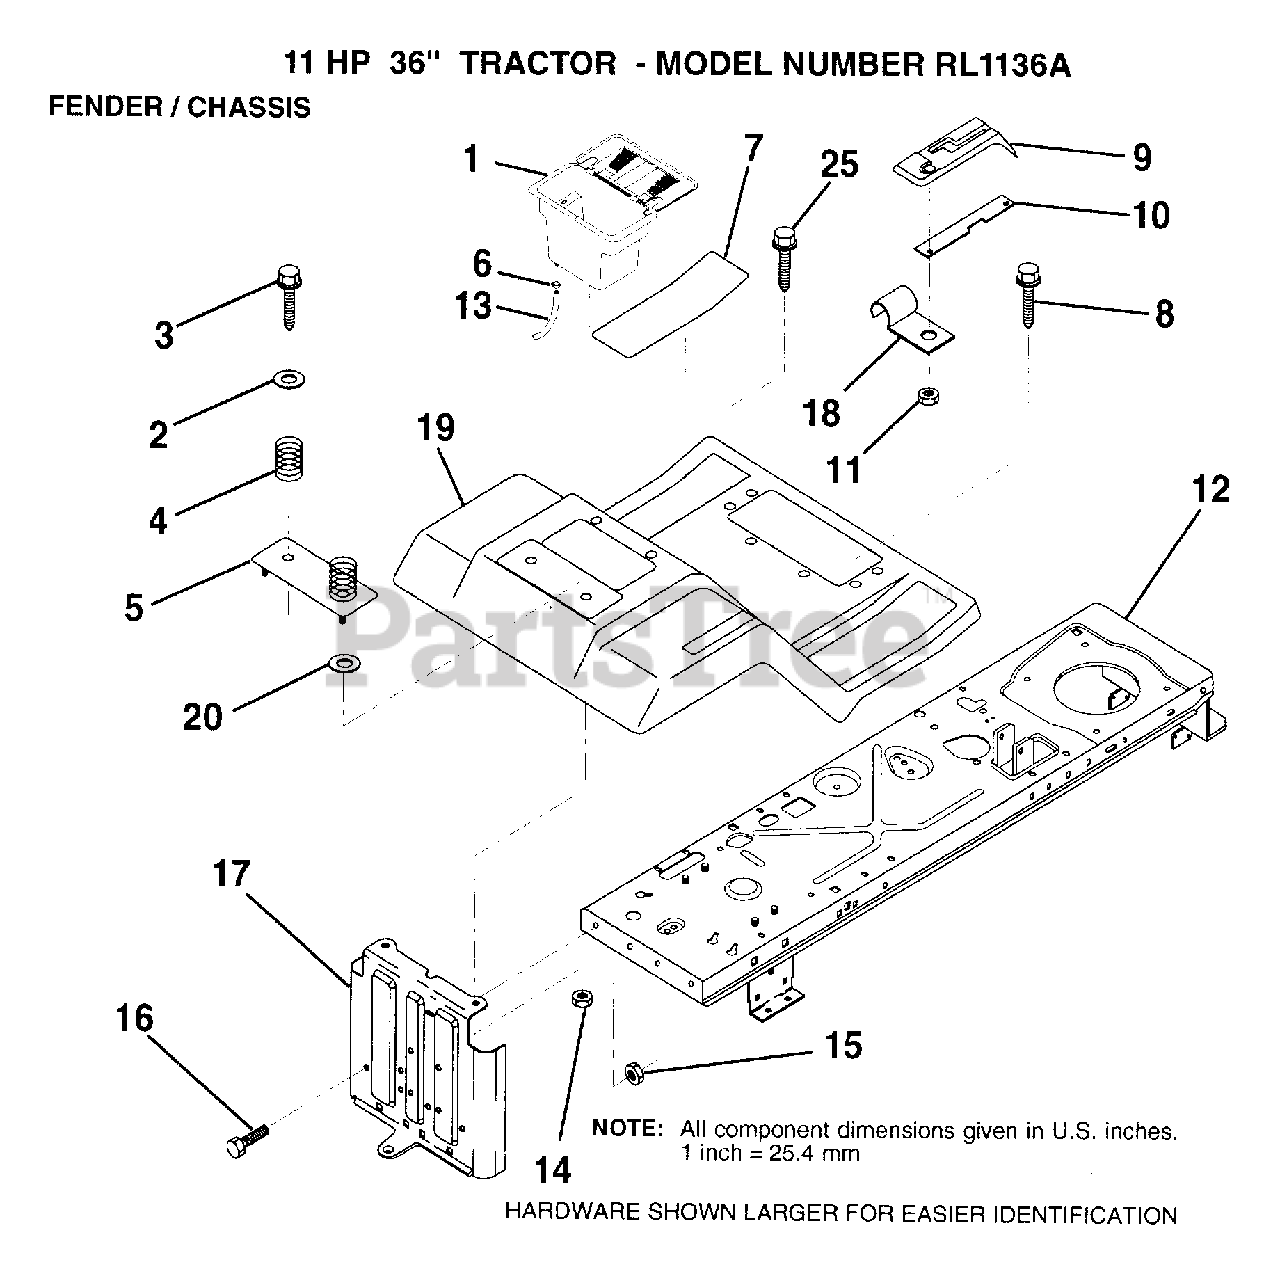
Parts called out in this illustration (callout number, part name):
2	WASHER
3	SCREW
4	SPRING COMPRESSIO
5	"PLATE, BATTERY"
6	HOSE CLAMP T
7	PAD FOOTREST
8	SCREW
11	NUT
13	TUBE T
14	NUT
16	BOLT
17	DRAWBAR
18	"CLIP,INSULATOR"
25	SCREW TI
